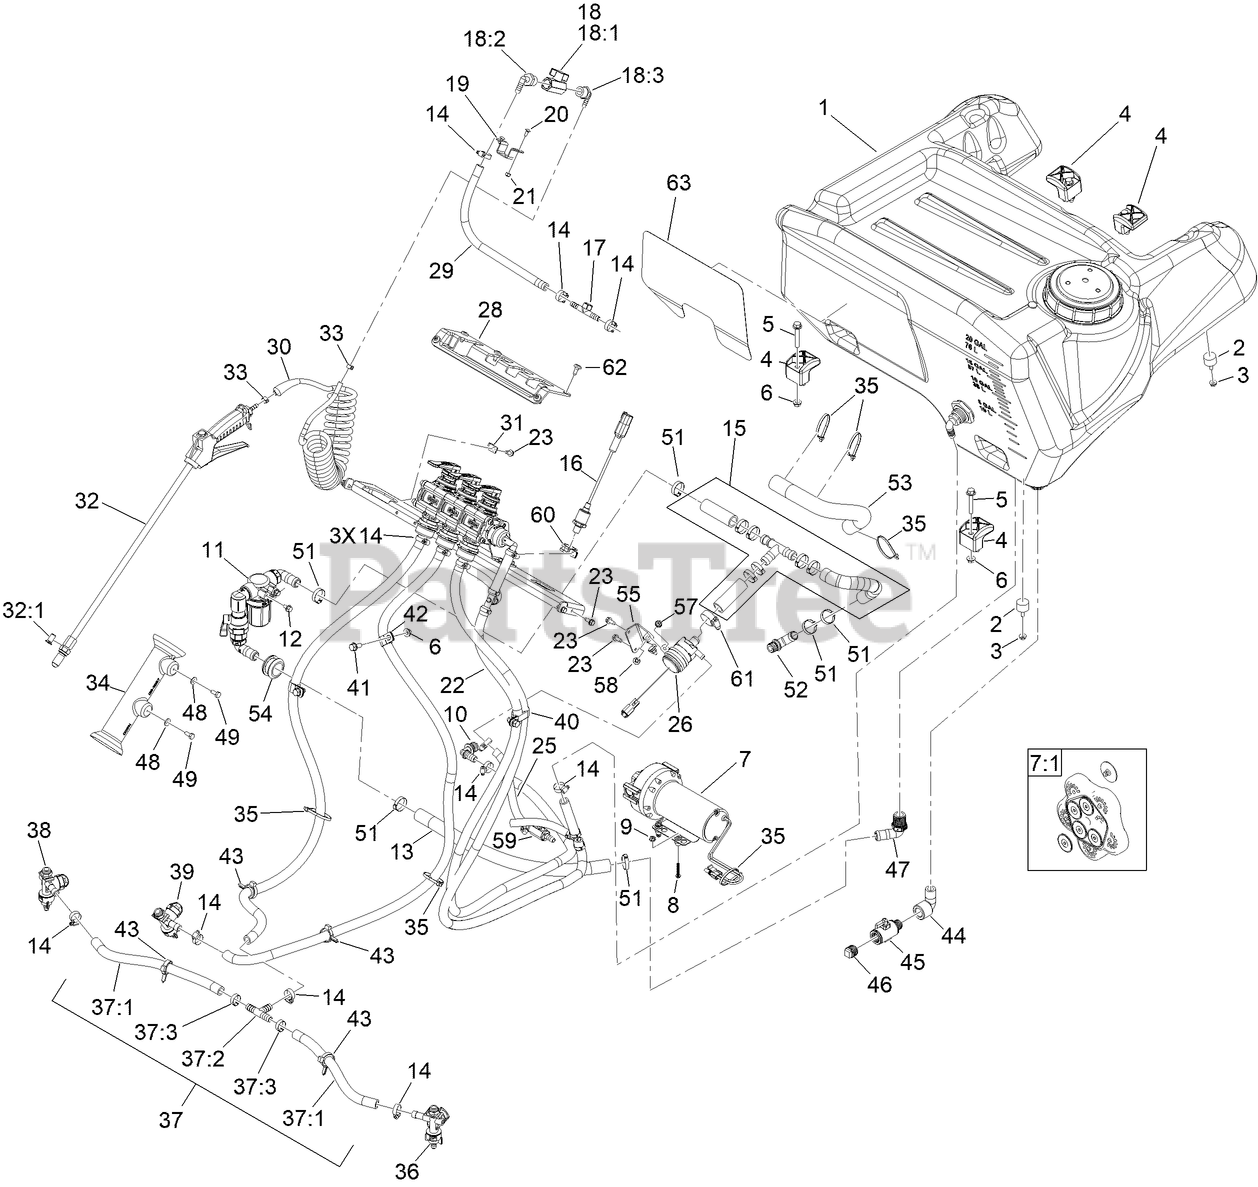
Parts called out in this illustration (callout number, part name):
1	TANK-SPRAYER
2	BUMPER
3	NUT-HF
5	SCREW-HHF
6	NUT-HF
7	PUMP-DIAPHRAGM, 3.8 GPM
7:1	KIT-DIAPHRAM PUMP
8	SCREW-SHWH
9	NUT-HF
10	FITTING-ELBOW, BARBED
11	STRAINER ASM
12	SCREW-HHF
13	HOSE-WATER
14	CLAMP-HOSE
15	ASM-, 3/4 PVC REINFORCED WATER HOSE
16	TRANSDUCER-PRESSURE
17	FITTING-TEE
18	WAND CONTROL ASM
18:1	VALVE-BALL
18:2	FITTING-ELBOW-90
18:3	FITTING-ELBOW-90
19	BRACKET-VALVE
20	BOLT-CARR
21	NUT-LOCK, NI
22	MANIFOLD-VALVE, CONTROL ASM
23	SCREW-HWH
25	HOSE-WATER
26	PUMP-CENTRIFUGAL
28	COVER-CONTROLS
29	HOSE-WATER, 3/8 PVC RED
30	HOSE-COILED
31	CLAMP-R
32	SPRAY WAND ASM
32:1	STRAINER-NOZZLE, 50M 5PSI CHECK
34	HOLDER-WAND
35	TIE-CABLE
36	LEFT NOZZLE SUB ASM
37	HOSE ASM
37:1	HOSE-WATER
37:2	FITTING-TEE
37:3	CLAMP OETIKER 0.716" CLOSED 0.826" OPEN
38	RIGHT NOZZLE SUB ASM
39	CENTER NOZZLE SUB ASM
41	SCREW-HHF
42	CLIP-LOOM
43	CLAMP-HOSE
44	ELBOW-90 DEG
45	MICROVALVE
47	ELBOW-HOSEBARB
48	WASHER-FLAT
49	SCREW-HH
52	FITTING-ELBOW
53	SLEEVE-CORRUGATED, SPLIT
54	GROMMET
55	BRKT-RECIR PUMP
57	NUT-HF
58	SCREW-CARR
59	VALVE-3/8 CHECK
60	R-CLAMP
61	CLAMP-HOSE
62	SCREW-SHOULDER
63	BARRIER-HEAT
